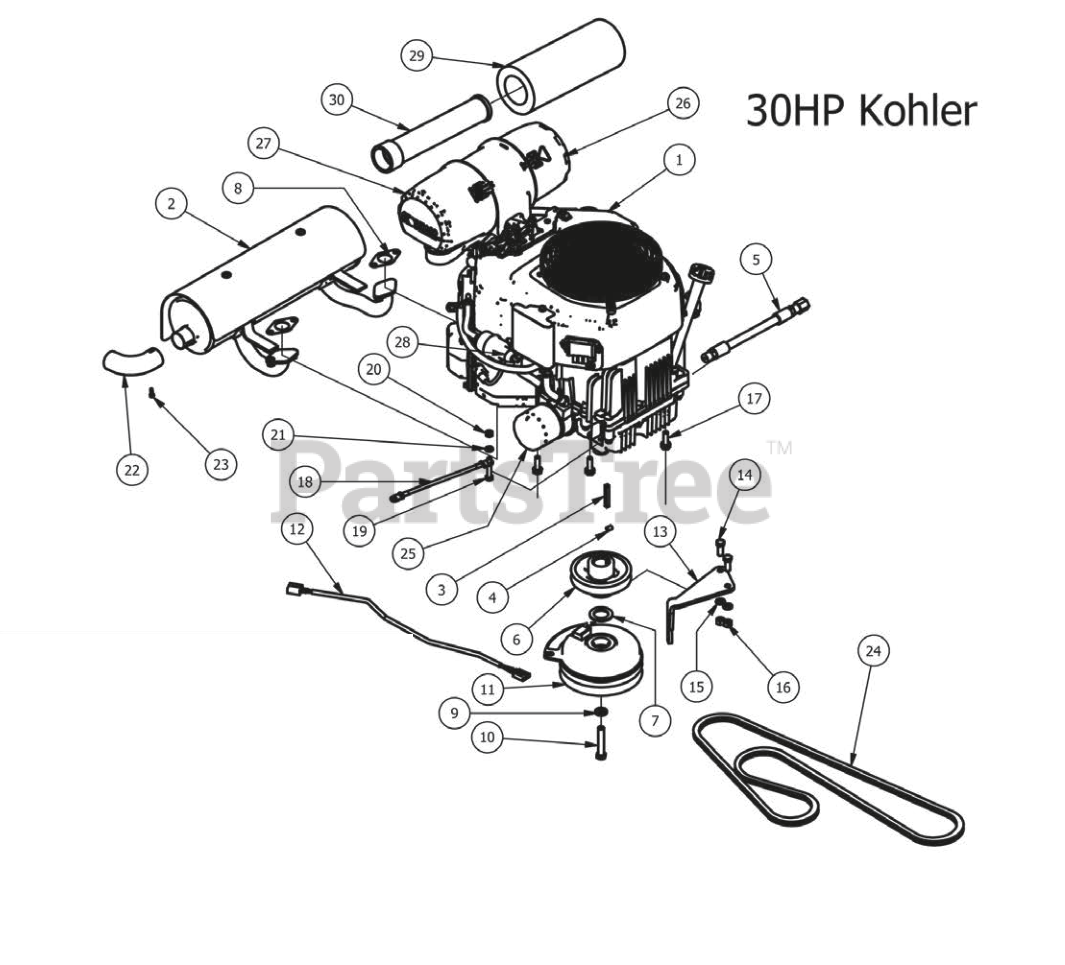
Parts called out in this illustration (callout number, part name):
1	30hp Kohler Engine
2	Exhaust 30 Kohler
3	1/4 x 2 Square key Stock
4	3/8" Set Screw
5	Oil drain Valve
6	4 3/4 Motor Pulley
7	11/8" Flat Spacer
8	Exhaust Gasket for 27, 30 HP
9	7/16" Lock Washer
10	7/16" x 2 1/2" Hex Bolt
11	Clutch Assembly
12	Clutch Pigtail
13	PTO Engager Holder
14	3/8" x 1" Hex Bolt
15	3/8" Lock Washer
16	3/8" Hex Nut
17	3/8 x 1 1/8 bolt
18	Starter to chassis cable
19	5/16" x 1 3/4" Hex Bolt
21	5/16" Lock Washer
22	Exhaust Extension
23	#10 x 1/2" Self Taping Screw
25	Oil Filter - 27&30 Kohler
26	30 Kohler End Cap- New Style
27	30 Kohler Air Canister
28	Universal inline Fuel Filter
29	Canister Air Filter-Outer
30	Canister Air Filter- Inner
